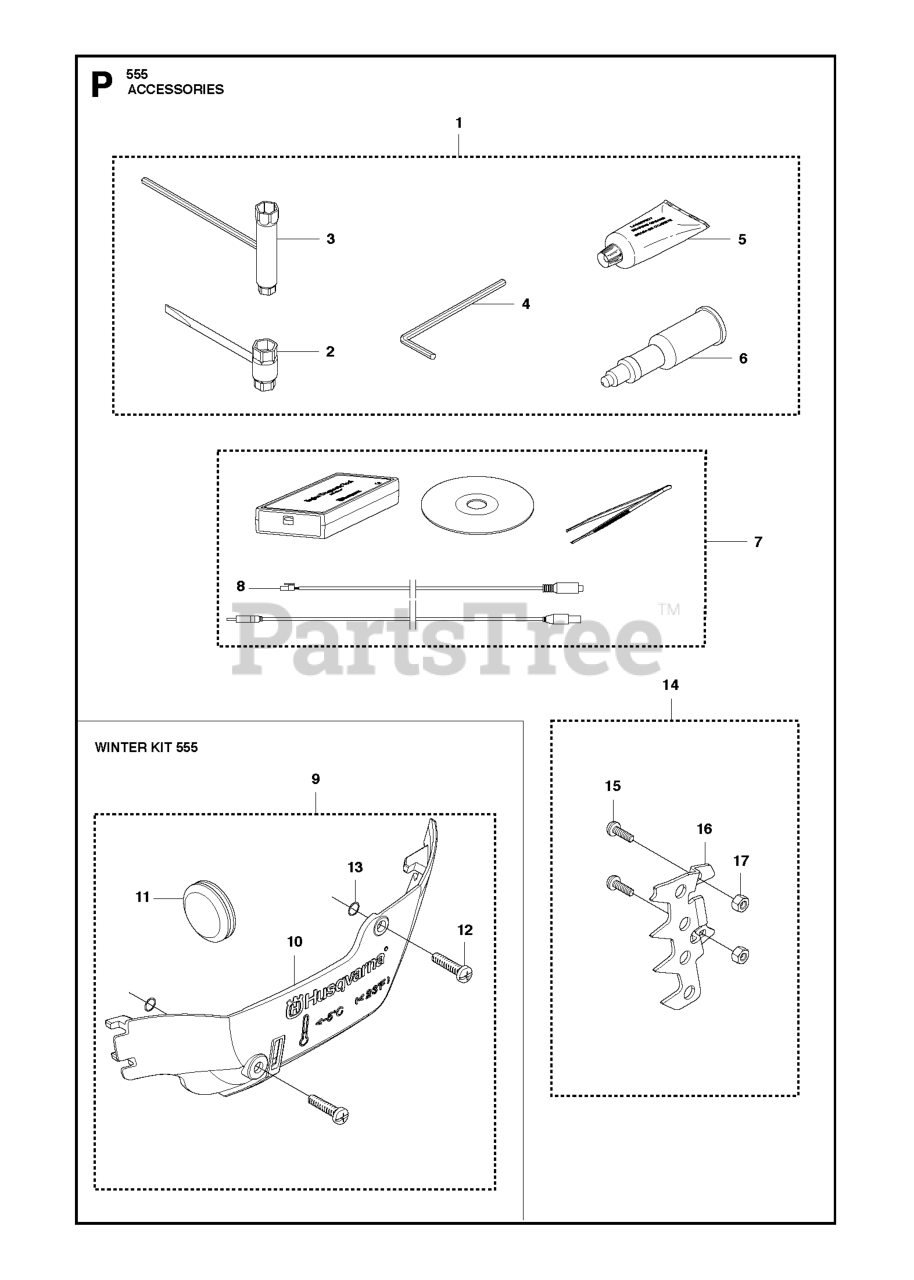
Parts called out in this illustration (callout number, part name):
2	COMBINATION WRENCH
3	L-SPANNER
4	L-SPANNER
5	GREASE
6	Grease Gun
7	SERVICE TOOLS
8	CABLE ASSY
9	WINTER KIT
10	WINTER COVER
11	PLUG
12	SCREW
13	O-RING
14	SPIKE OUTER
15	SCREW
16	SPIKE OUTER
17	NUT
